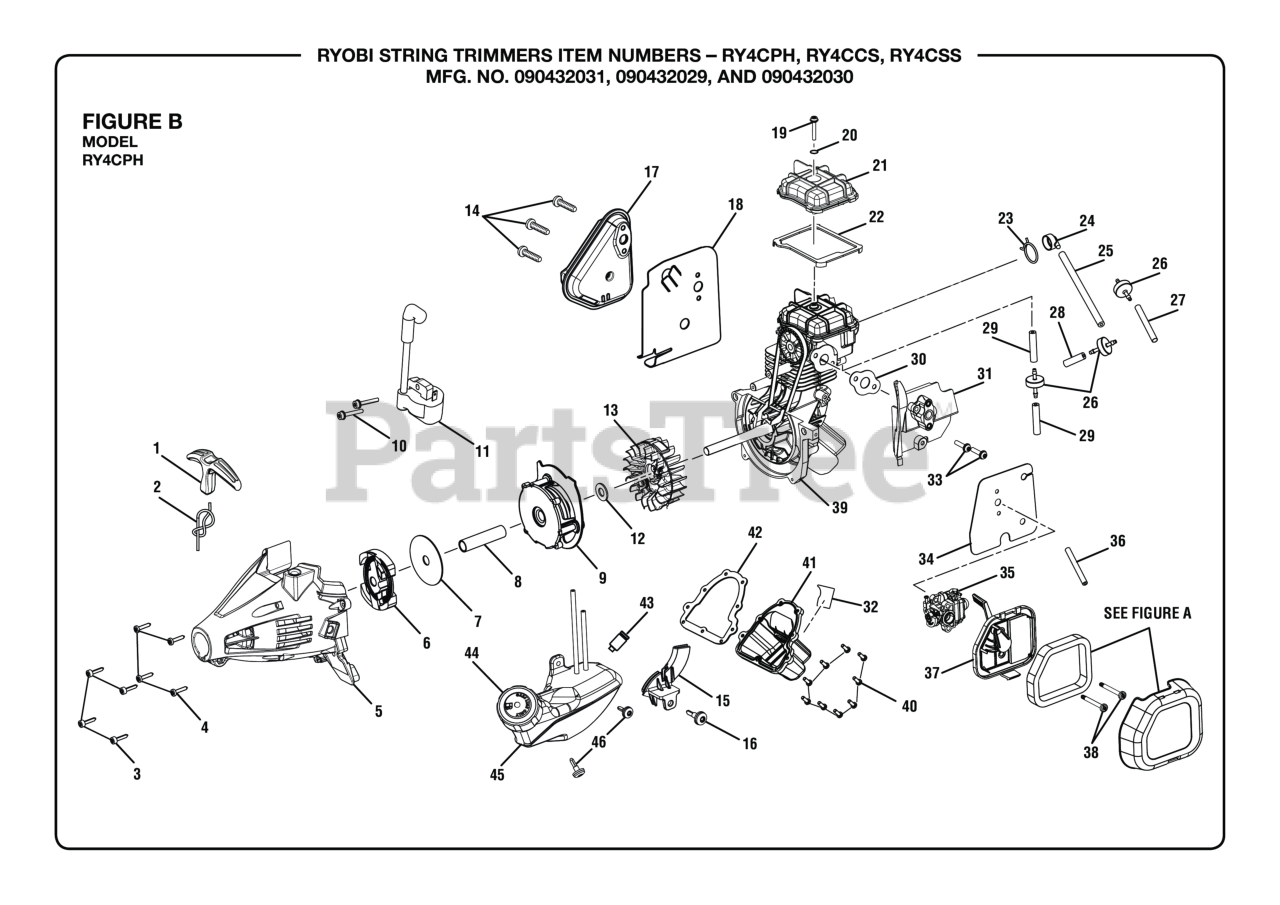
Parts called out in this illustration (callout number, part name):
1	Pulley Handle
2	STARTER ROPE 42 (PKG)
3	Screw (M4 x 18 mm, T20 Torx Pan Hd. S.T.)
4	Screw w/Washer (M4 x 16 mm, T25 Torx Truss Hd.)
5	Starter Housing Assembly
6	CLUTCH ASSEMBLY
7	Washer (ID9.63 x OD50.75 x 1.10t)
8	Spacer Tube
9	Starter Housing Assembly
10	Screw w/Washer (M4 x 19 mm, T20 Torx Pan Hd. S.T.)
11	Ignition Module
12	Washer (ID9.75 x OD20 x 1.6t)
13	Flywheel Assembly
14	Screw (M5 x 38 mm, T25 Torx Truss Hd.)
15	Throttle Cable Guide
16	Shoulder Screw (M4 x 19 mm, T25 Torx Truss Hd.)
17	Muffler Assembly
18	Muffler Gasket
19	Screw (M4 x 27 mm Total, w/14 mm Threaded)
21	Cam Cover
22	Cam Cover Gasket
23	Wire Clamp
24	Breather Fitting
25	Breather Hose (120 mm)
26	Check Valve
27	Shield Sleeve (M6 x 50 mm)
28	Breather Hose (24 mm)
29	Breather Hose (34 mm, Crankcase)
30	Heat Dam Gasket
31	Heat Dam
32	Hot Surface Label
33	Screw (M5 x 23 mm, T25 Torx Pan Hd.)
34	Heat Shield w/Gasket (Carburetor)
35	Carburetor
36	Breather Hose (50 mm)
37	Air Box Base Assembly
38	Screw (M5 x 44 mm,T25 Torx Hd. Carburetor)
39	Short Block Assembly
40	Screw (M4 x 12 mm, T20 Torx Hd.)
41	Oil Pan (Inc. Key No. 47)
42	Oil Pan Gasket
43	Fuel Filter
44	Fuel Cap Assembly
45	Fuel Tank w/Cap (Inc. Key Nos. 43-44)
46	Shoulder Screw w/Washer (M4 x 14 mm, T25 Torx Truss Hd.)
